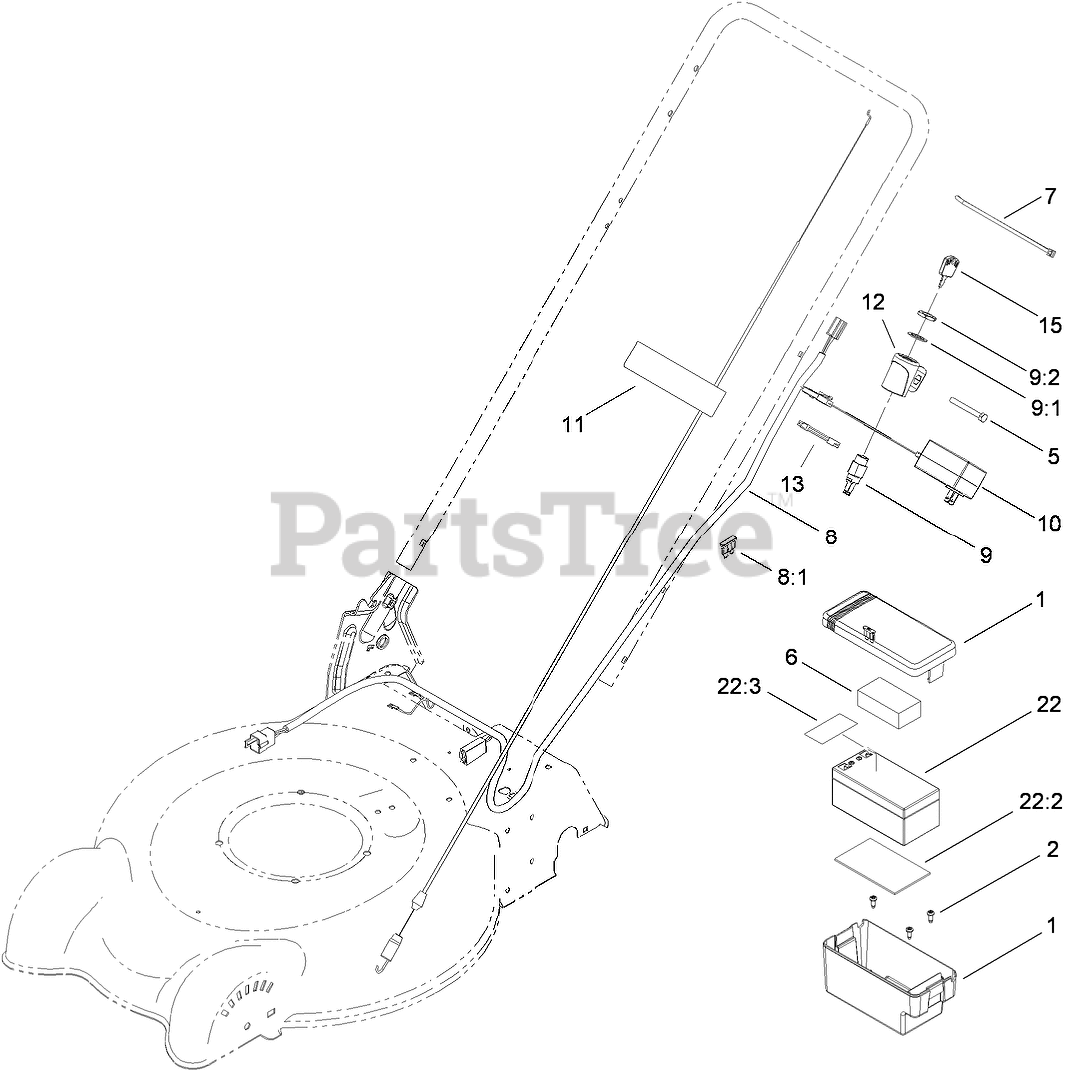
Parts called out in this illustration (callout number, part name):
1	BATTERY BOX ASM
2	SCREW-FORMING, THREAD
5	SCREW-HH
6	FOAM-BATTERY, TOP
7	TIE-CABLE
8	HARNESS-WIRE
8:1	FUSE-40 AMP
9	STARTER SWITCH ASM
9:1	WASHER-TOOTH, INTERNAL
9:2	NUT-HH
10	CHARGER-EUROPEAN, 12V DC
11	DECAL-WARNING
12	MOUNT-SWITCH
13	ADAPTER-CHARGER
22	BATTERY
22:2	FOAM-BATTERY
22:3	DECAL-TERMINAL, BATTERY
